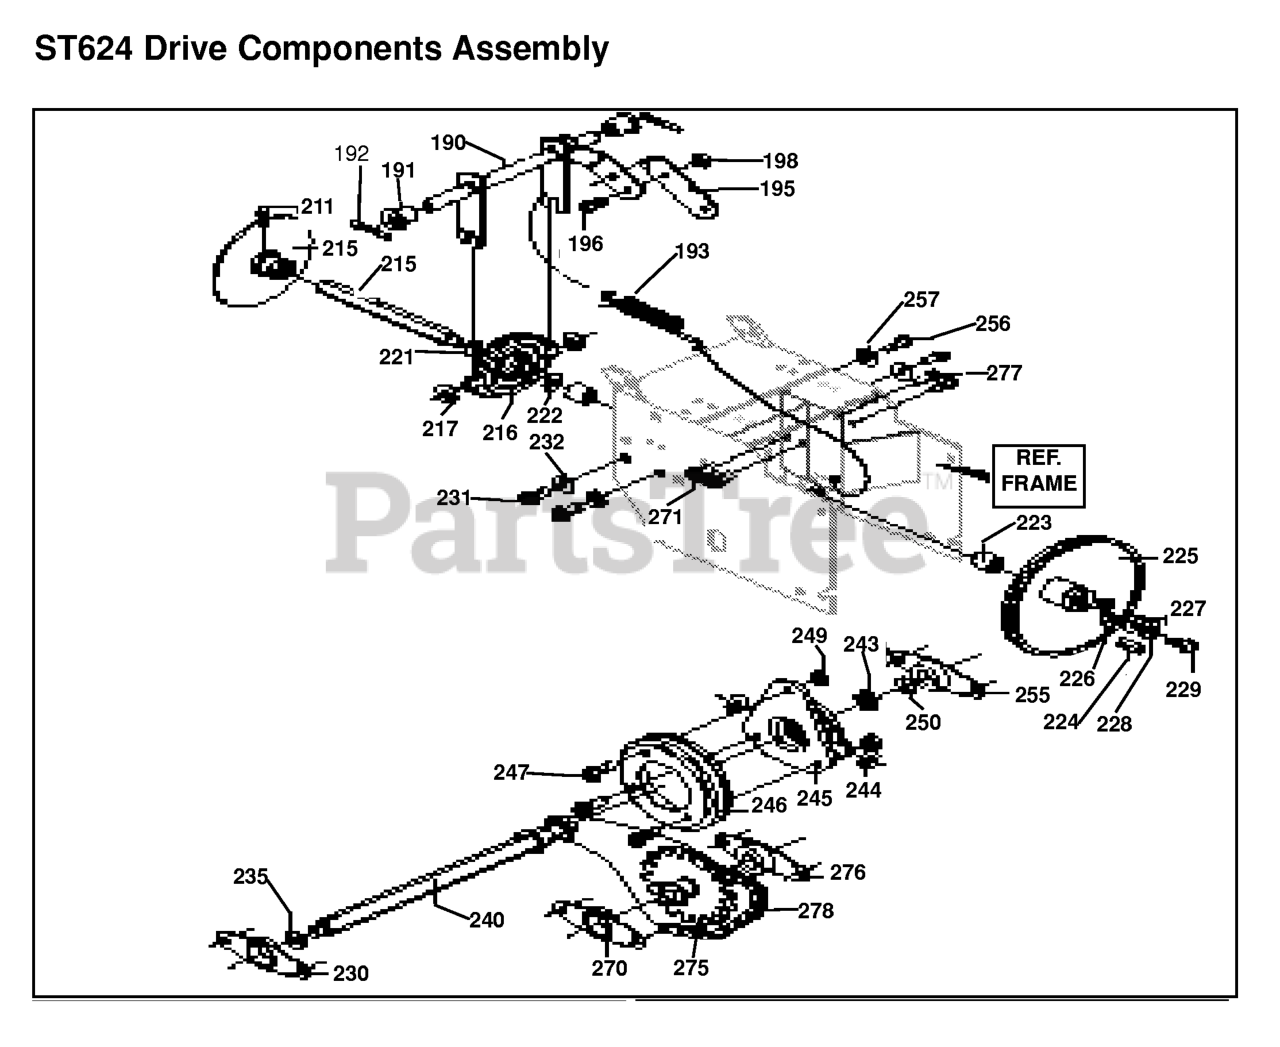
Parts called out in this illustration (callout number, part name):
191	FLANGE BEARING
192	COTTER PIN .125 X 1.0
210	DISC, ASSY FRICWHL
211	GREASE FITTING
223	BEARING
224	SQUARE KEY
227	WASHER, FLAT .281 X1.00X.083
228	WASHER, REGSPTLK.263X.49X
229	SCREW, 1/4-20X .75 HHC
230	BEARING & RETAINER ASSY
231	SCREW, 5/16-18X .50 WAHHT
232	WASHER, HVSPTLK .328X.60X
240	WF HEX, ASM#40-8TW/PB
243	RING, RETEX
245	BEARING, TRUNION CLUTCH
246	FRICTION DISC
249	NUT, 1/4-20 HEX KEPS
255	BEARING & RETAINER ASSY
256	SCREW, 5/16-18X .50 WAHHT
257	WASHER, HVSPTLK .328X.60X
270	BEARING & RETAINER ASSY
271	SCREW, 5/16-18X .50 WAHHT
275	JACK, ASSY #41-36T & 8T
276	BEARING & RETAINER ASSY
277	SCREW, 5/16-18X .50 WAHHT
